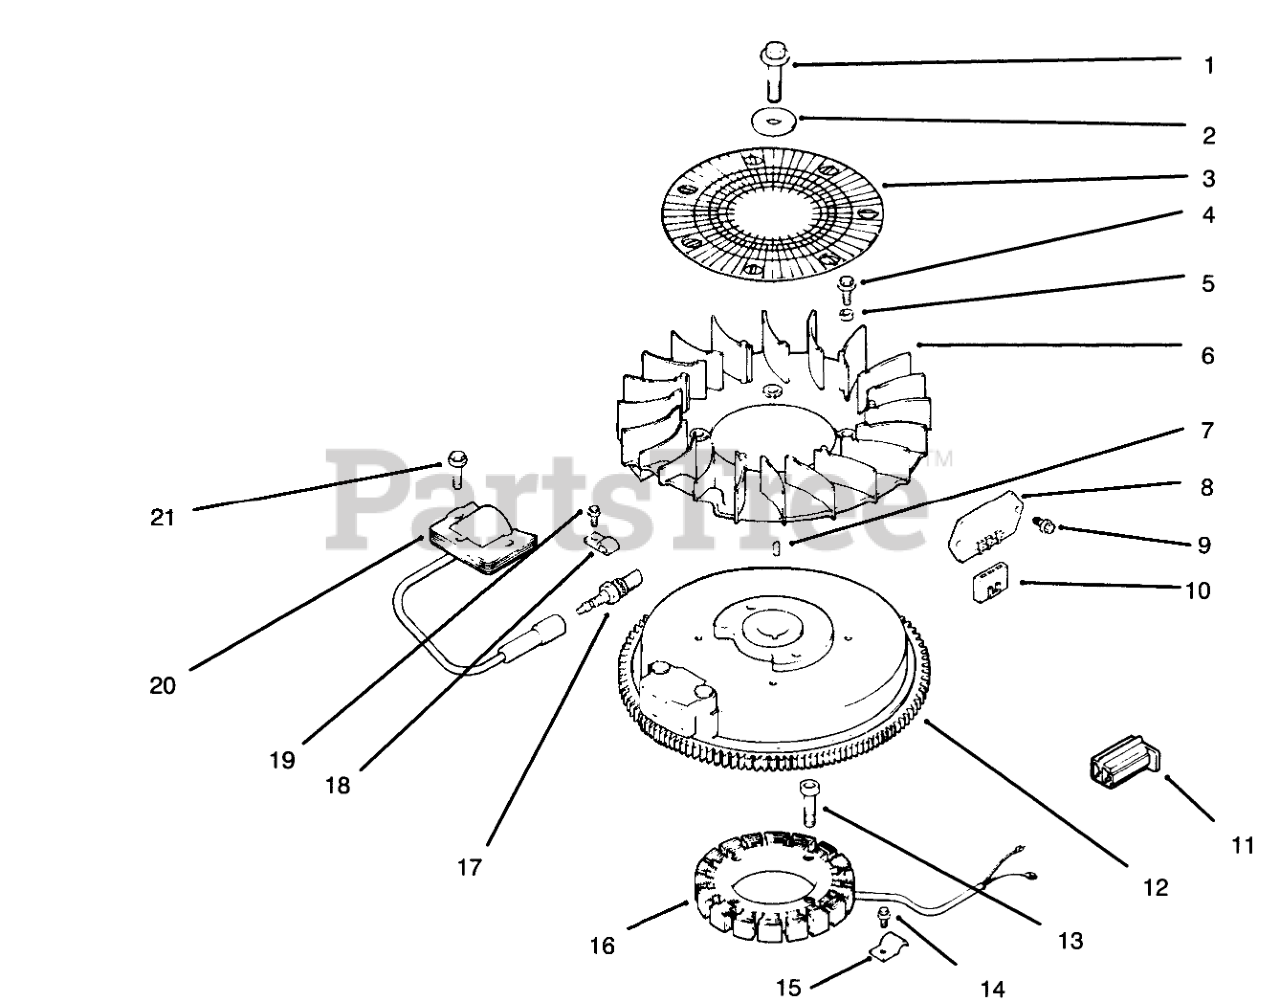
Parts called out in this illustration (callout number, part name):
1	Screw
3	Screen-Grass
4	Screw-Fan
5	Spacer-Fan
6	Fan
7	Key
8	Rectifier-Unregulator
9	Screw
10	Connector
11	Connector
12	Flywheel
13	Screw
15	Clip
16	Stator 15 amp.
17	Spark Plug
18	Clip
20	Module-Ignition
21	Screw
